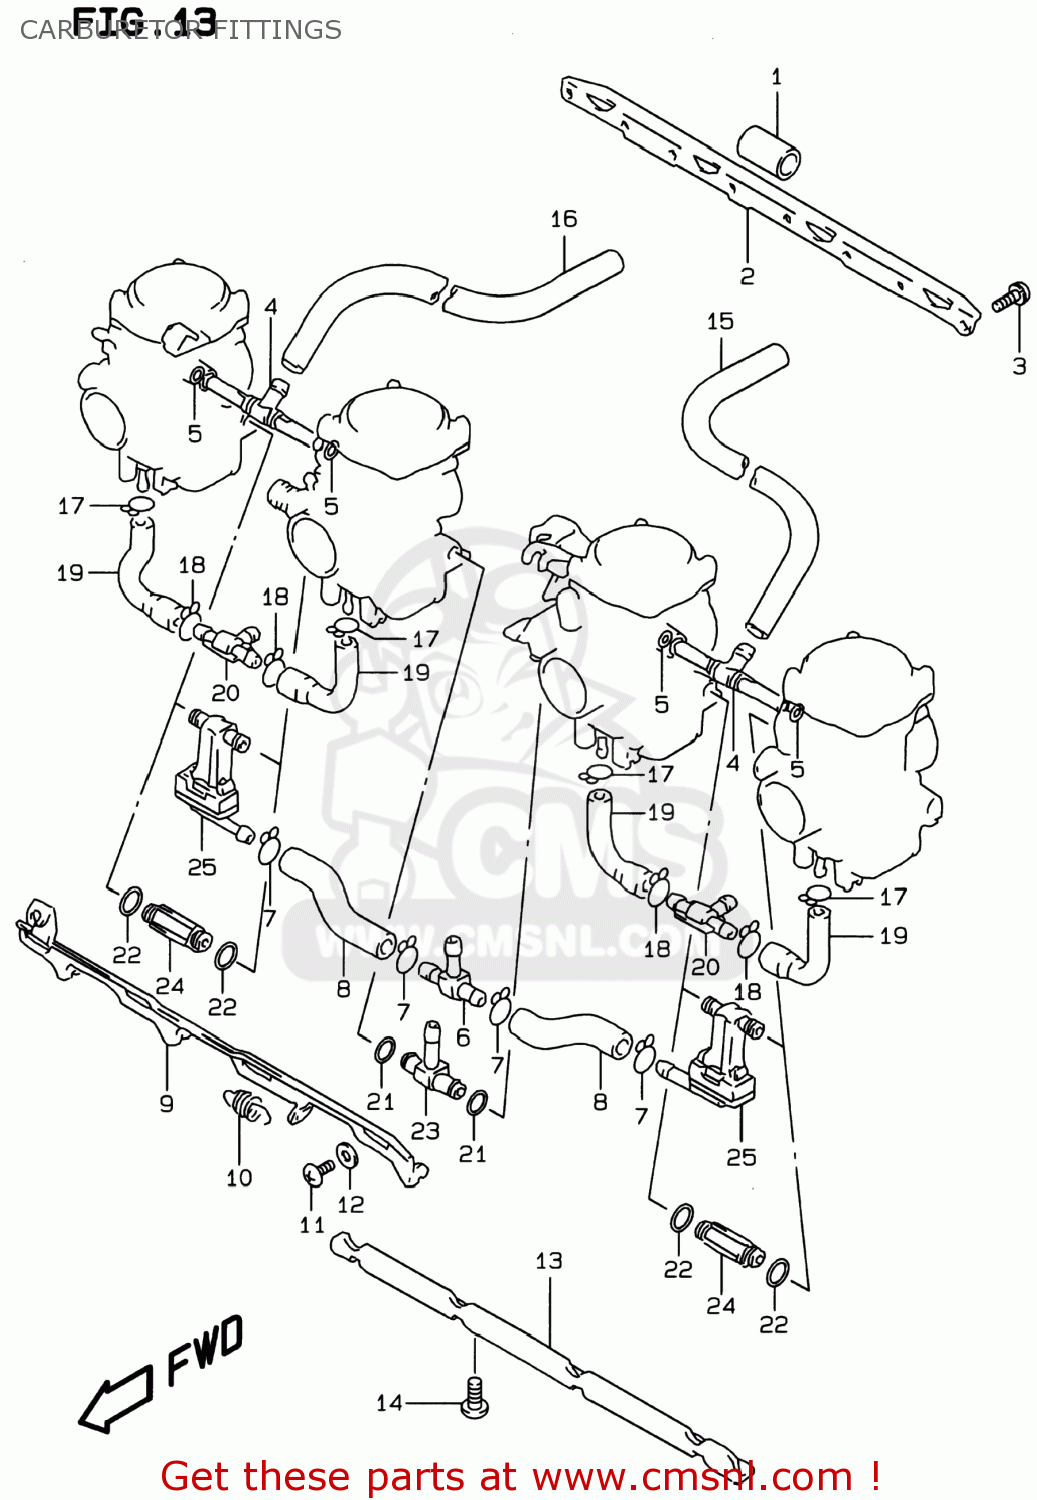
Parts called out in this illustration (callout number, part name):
1	PIPE
2	STAY,PLATE
3	SCREW
4	JOINT
5	O RING
6	JOINT
7	CLAMP
8	HOSE
9	LEVER,STARTER
10	SPRING
11	SCREW
12	WASHER
13	STAY,PLATE
14	SCREW
15	HOSE(7X11X600)
16	HOSE(7X11X600)
17	CLIP
18	CLIP
19	HOSE
20	JOINT
21	O RING
22	O RING
23	JOINT
24	JOINT
25	JOINT SET
